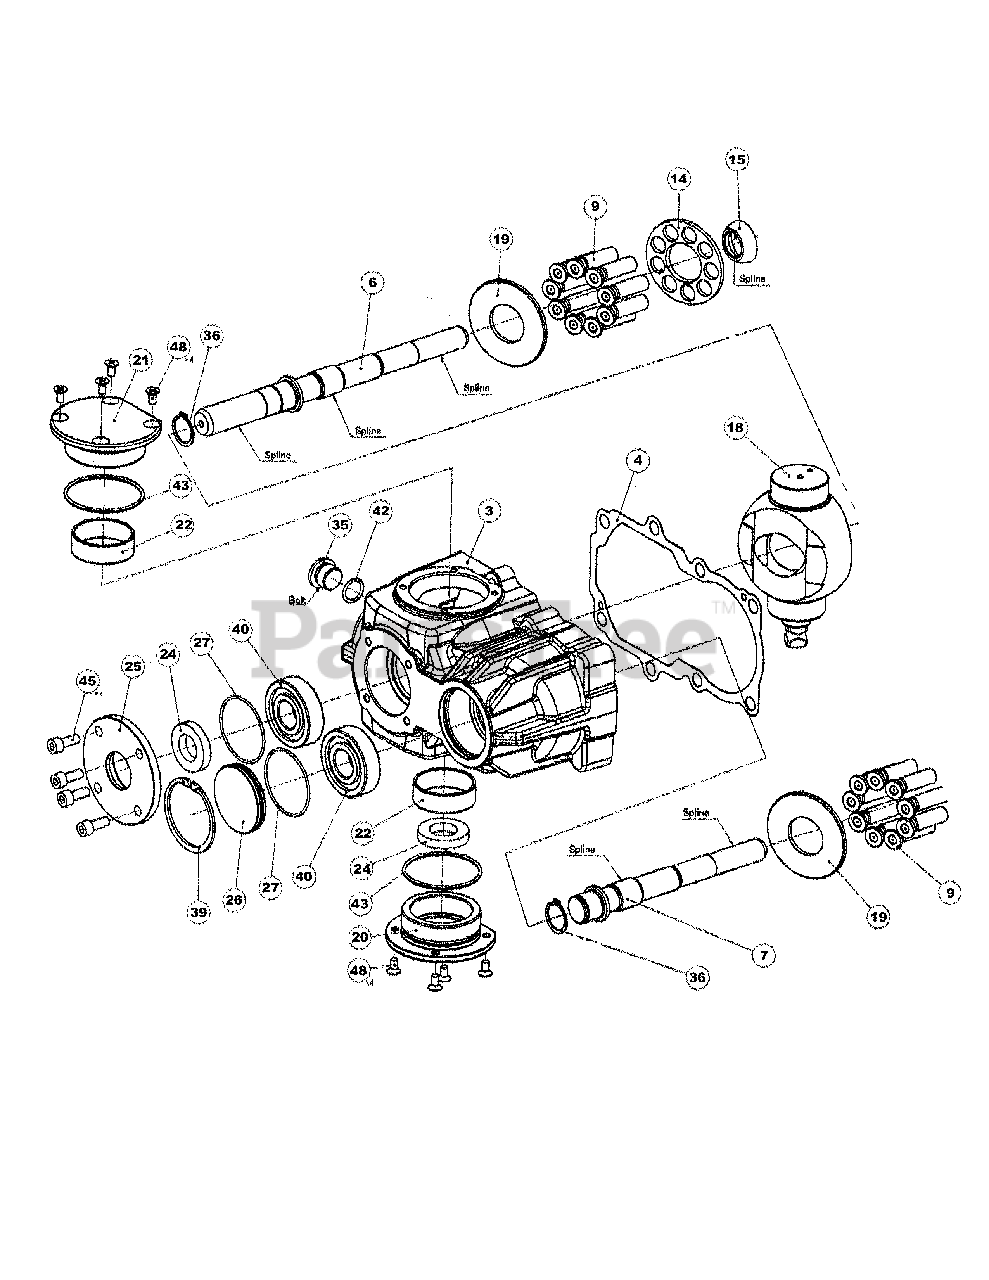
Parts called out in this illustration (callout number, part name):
1	Plug PF3/8
2	Center section
3	Housing
4	Housing packing
5	Pin 4 x 14
6	Input shaft
7	Shaft
8	Needle bearing
9	Plunger assembly
10	Plunger spring
11	Spring retainer
12	Plunger block
13	Pin
14	Retainer
15	Retainer washer
20	Cover
21	Cover
22	Bush
23	Seal 20 x 35 x 8
24	Seal 25 x 45 x 8
27	O-ring S58.2
28	Neutral and Check Relief (NCR) valve + 0.7
29	Spring (Check valve)
30	Plug
31	Retainer
32	Valve spring
33	Valve assembly
36	Ring 25
37	Ring 32
40	Bearing 6305 C3NTN
41	Packing P 14.0
42	Packing P 18.0
43	Packing G 65.0
44	Bolt 6 x 10
48	Screw 6 x 12
